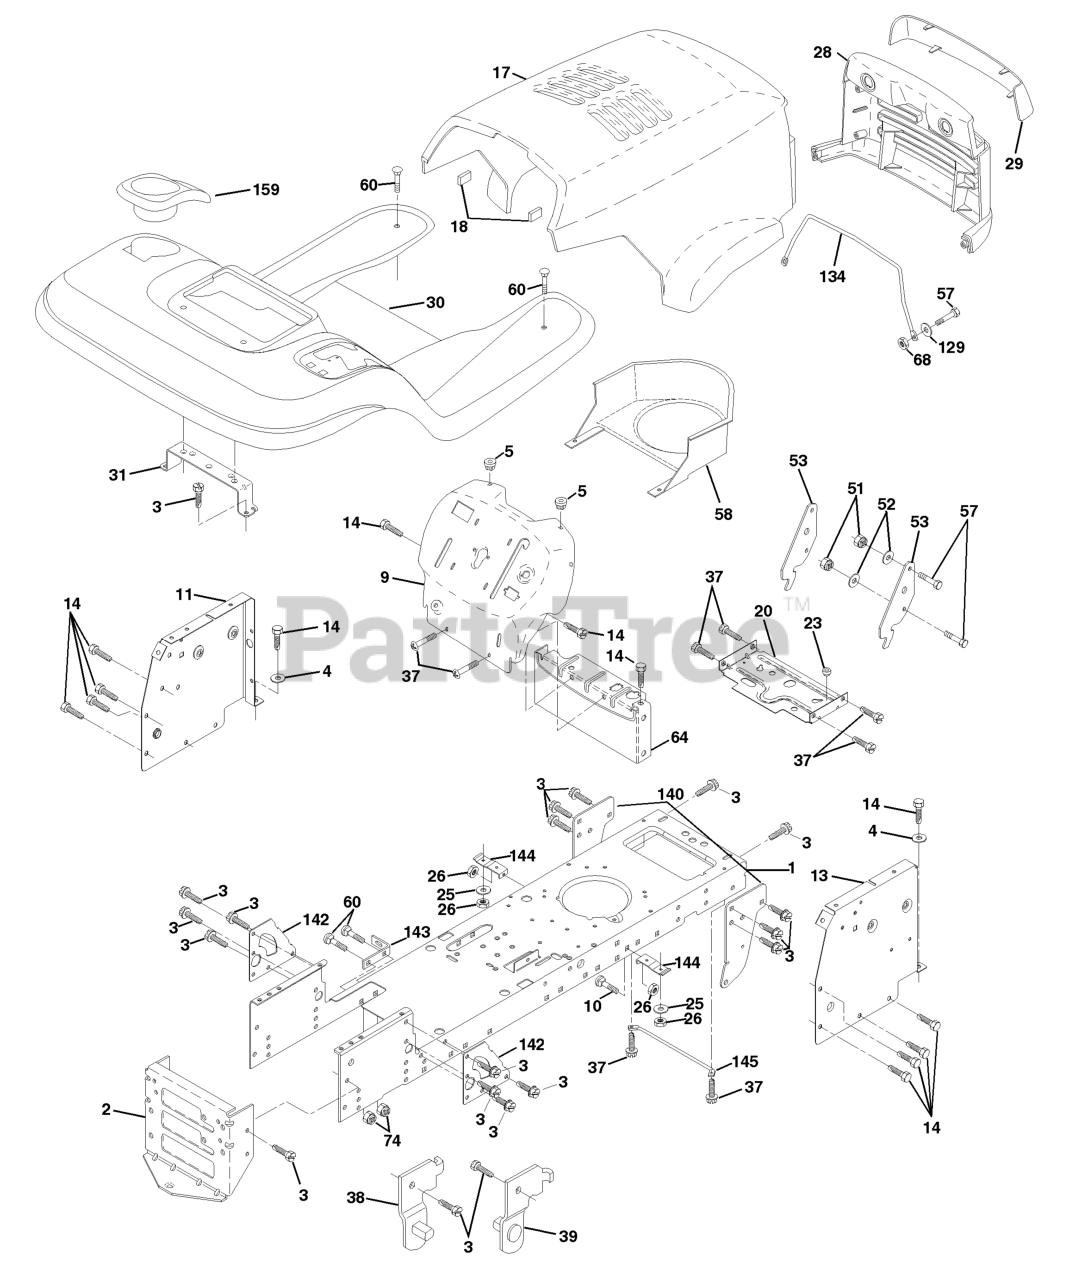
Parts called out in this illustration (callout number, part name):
2	STRETCH DRAWBAR
3	SCREW
4	Washer 13/32 x 3/4 x 16 Ga.
5	BUMPER.RUBBER.HOOD
9	DASH PANEL
10	BOLT D
11	PANEL DASH LH
13	PANEL DASH RH
14	SCREW LT
17	HOOD
18	BUMPER HOOD T
20	PLATE MTG
23	BUSHING.SNAP.NYL.BLK.
25	WASHER
26	NUT
28	GRILL
29	LENS
30	FENDER
31	BRACKET.SUPPORT.FENDER
37	Screw Thdrol 6/16-18 x 1/2 TYT
38	BRACKET LH PIVOT
39	BRACKET RH PIVOT
51	LOCKNUT.NYLOC.1/4-20
52	WASHER
53	BRACKET PNT PICK OFF LT/PL
57	BOLT
58	AIR DUCT P/L/LT
60	Bolt Rdhd Sqnk 3/8-16unc x 3/4
64	DASH LOWER
68	NUT
129	WASHER
134	ROD SUPPORT HOOD LT/PL HUS.
140	BRACKET SUSPENSION FRONT
142	PLATE
143	BRACKET, SWAY BAR
144	BRACKET FOOTREST
145	ROD PIVOT CHASSIS/HOOD
159	CUPHOLDER
